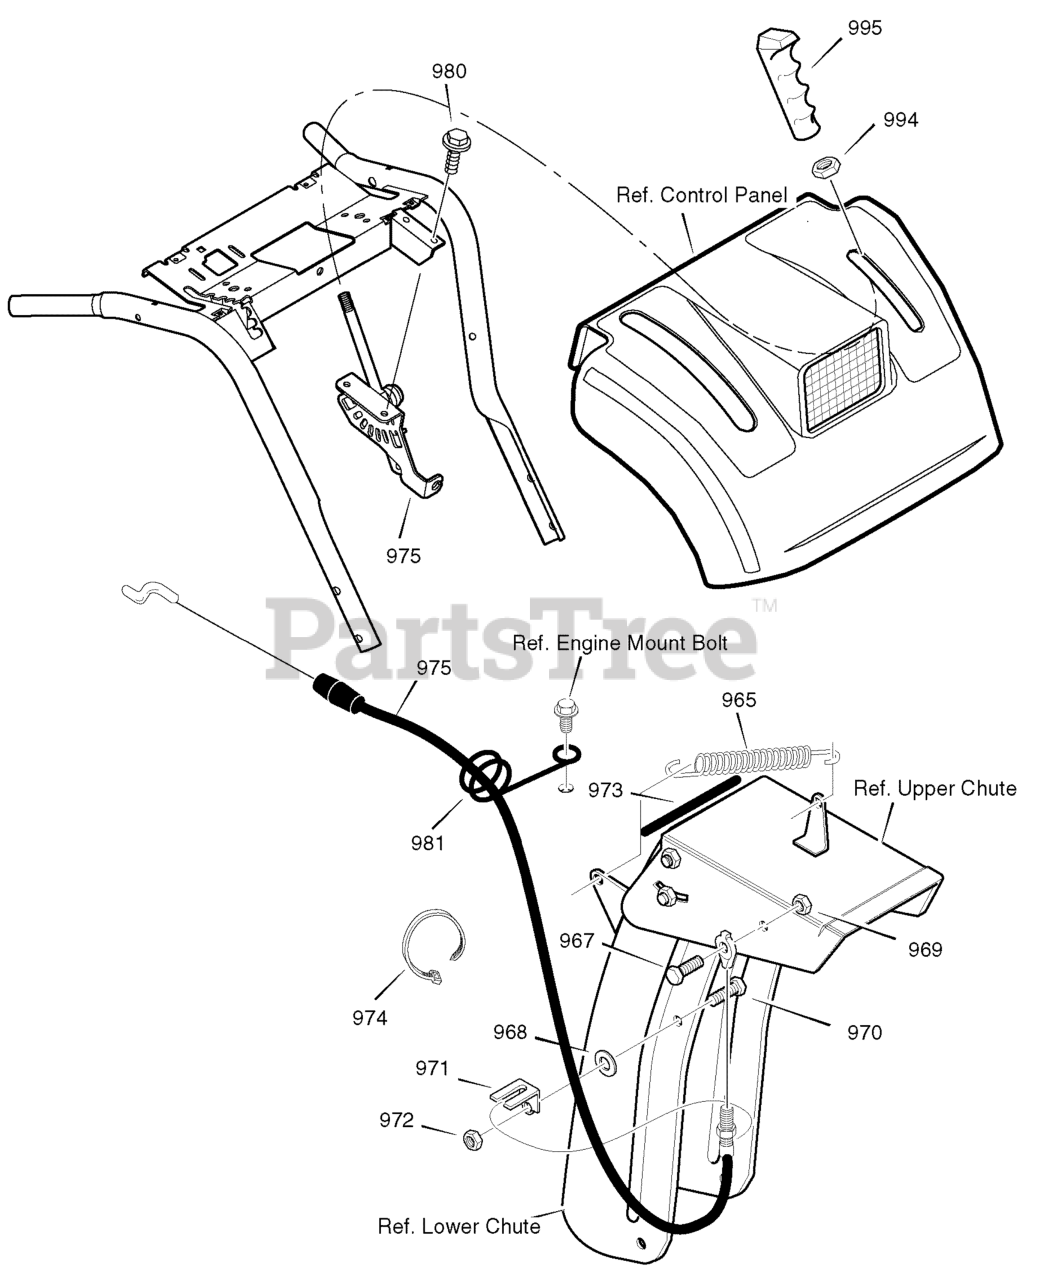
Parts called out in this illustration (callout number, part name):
965	TENSION SPRING
967	BOLT, SHOULDER
968	FLATWASHER
969	NUT
970	SCREW, 5/16-18 x 0.75
971	BRACKET, CABLE CHUTE
972	NUT, 5/16-18
973	TRIM STRIP, BLACK
974	TIE, CABLE
975	CABLE, CHUTE DEFLECTOR
981	WIRE FORM, CHUTE CABLE
994	NUT, 3/8-16
995	KNOB, SHIFT
